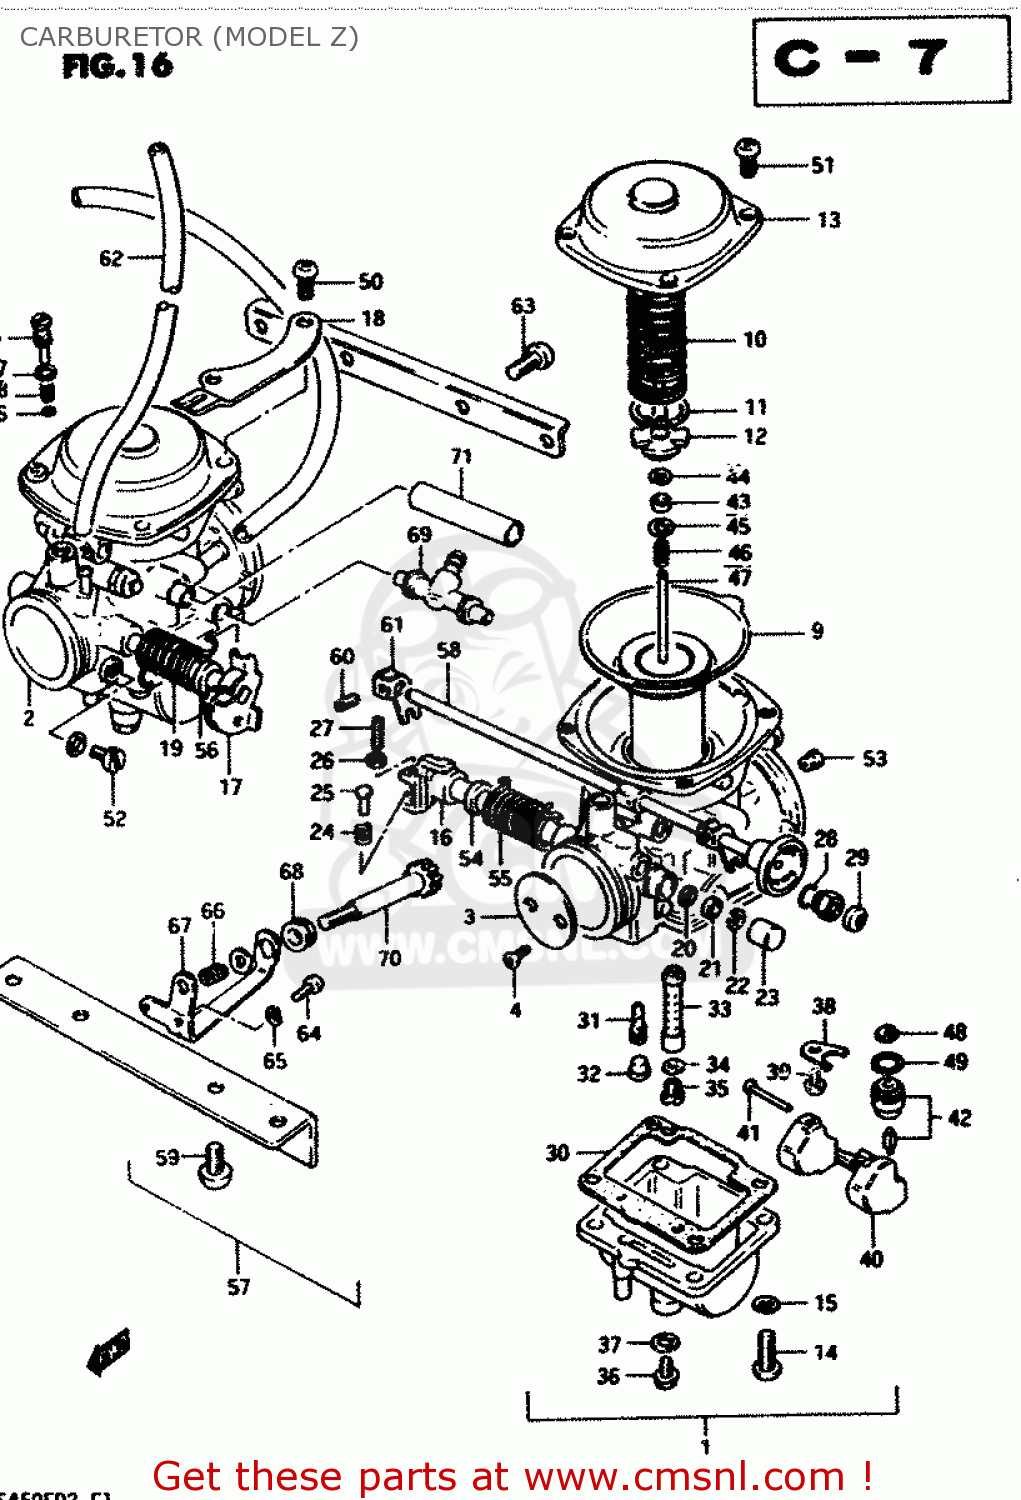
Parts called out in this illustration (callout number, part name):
1	CARBURETOR ASSY, LH
2	CARBURETOR ASSY, RH
3	VALVE, THROTTLE
4	SCREW
5	SCREW,PILOT AIR
6	O-RING
7	GASKET
8	SPRING
9	DIAPHRAGM ASSY
10	SPRING
11	E RING
12	HOLDER,GUIDE
13	COVER
14	SCREW
15	LOCK WASHER
16	SHAFT ASSEMBLY
17	SHAFT,THROTTLE
18	BRACKET
19	SPRING
20	SEAL
21	GASKET,THROTTLE SHAFT (NAS)
22	E RING
23	CAP
24	SPRING,THROTTLE SCREW
25	PIN,THROTTLE LEVER
26	NUT
27	SCREW
28	O RING
29	CAP,STARTER VALVE
30	GASKET,FLOAT CHAMBER (NAS)
31	JET,PILOT(45)
32	PLUG,NEEDLE JET
33	JET,NEEDLE(O-9)
34	WASHER,NEEDLE NOZZLE
35	JET
36	PLUG,DRAIN
37	GASKET (NAS)
38	PLATE,NEEDLE VALVE FITING
39	SCREW 4X6
40	FLOAT
41	PIN,FLOAT
42	VALVE ASSEMBLY,NEEDLE
43	RING
44	CLIP
45	WASHER,JET NEEDLE
46	SPRING
47	NEEDLE, JET
48	FILTER
49	O-RING,NEEDLE VALVE
50	SCREW
51	SCREW
52	SCREW
53	JET,AIR(135)
54	SPACER,THROTTLE SHAFT
55	SPRING
56	SPACER,THROTTLE SHAFT
57	FLANGE ASSEMBLY,CARBURETOR
58	SHAFT,STARTER
59	SCREW 6X12
60	SCREW
61	LEVER
62	HOSE
63	SCREW
64	SCREW
65	LOCK WASHER
66	SPRING,THROTTLE ADJUST
67	BRACKET,THROTTLE ADJUST
68	CAP,RUBBER
69	NIPPLE,CARBURETOR
70	SCREW
71	HOSE
